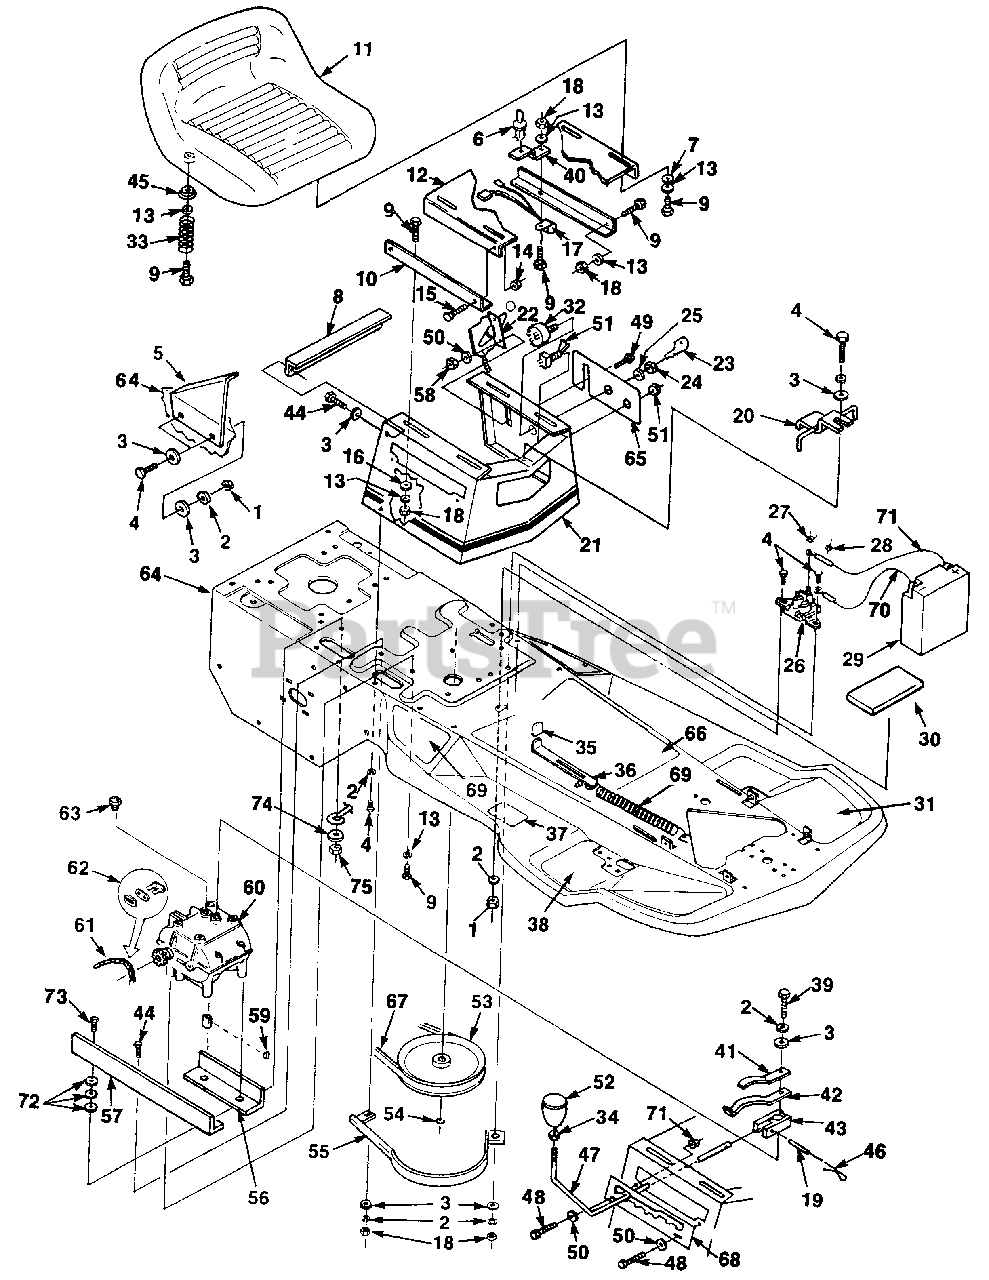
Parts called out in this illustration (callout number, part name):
1	NUT-Hex 1/4-20
2	WASHER-Lock 1/4
3	WASHER- Flat 1/4
4	SCREW-1/4-20 x 5/8
5	BRACKET- Chain guard
6	SWITCH- Seat
7	WASHER-Flat
8	BRACKET- Reinforcement
9	SCREW- 5/16-18 x .750
10	SEAT RAIL
12	BRACKET- Seat
13	WASHER- Lock 5/16
14	NUT- Centerlock hex 5/16-18
15	BOLT- Shoulder 5/16-18 hex
16	WASHER- Flat 5/16
17	NEUTRAL START (Safety Mod)
18	NUT- 5/16-18 hex
19	PIN- Spring 3/16 x 1
20	BRACKET- Battery
21	SUPPORT- Seat
22	THROTTLE CONTROL & CABLE
23	KEY- Ignition
24	NUT- Ignition switch 5/8-32
25	WASHER- Ignition switch 5/8
26	SOLENOID- Switch
27	NUT (Lead 1/4-20)
28	NUT (Hex 8-32)
30	BATTERY PAD
31	FOOT REST (left hand)
32	IGNITION SWITCH
33	SPRING- Torsion
34	NUT- Hex jam 3/8-24
35	KNOB- Latch
36	LATCHING- Parking brake
38	FOOT REST (right hand)
39	SCREW- Hex hd 1/4-28 x 7/8
40	BRACKET- Seat switch
41	SPRING LEAF
42	SPRING LEAF
43	BRACKET- Pivot
44	SCREW- Hex cap 1/4-20 x 3/4
45	RETAINER- Spring
46	PIN- Cotter
47	GEARSHIFT LEVER
48	SCREW 10-24 x 1/2
49	SCREW 10-24 x 1/2
50	WASHER- Flat 1/4 #10
51	SWITCH- P.T.0.
52	KNOB- Shift lever
53	TRANSMISSION PULLEY
54	RING-Snap
55	BELT GUIDE- Transmission
56	ANGLE- Short
57	ANGLE- Long
58	NUT-10-24
59	KEY- Transmission 3/16 x 3/4
60	TRANSMISSION- Peerless Tecumseh
61	CHAIN - Drive #40
62	CONNECTING LINK- Chain
63	SWITCH- Neutral safety
65	DECAL- Ignition Switch
66	DECAL- Instruction
67	BELT- Transmission
68	PLATE- Shift
69	SPRING- Extension
70	CABLE- Ground
71	CABLE- Battery
73	SCREW
74	WASHER- 3/8 Flat
75	NUT- Hex Centerlock 3/8-16
